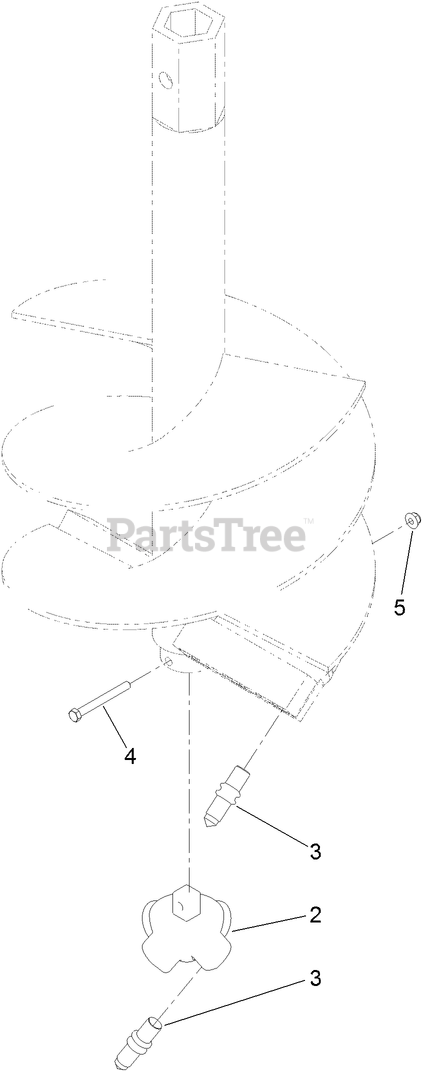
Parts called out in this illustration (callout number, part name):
2	PILOT-AUGER, ROCK
3	TOOTH-BULLET
4	SCREW-HH
5	NUT-HF, NI
